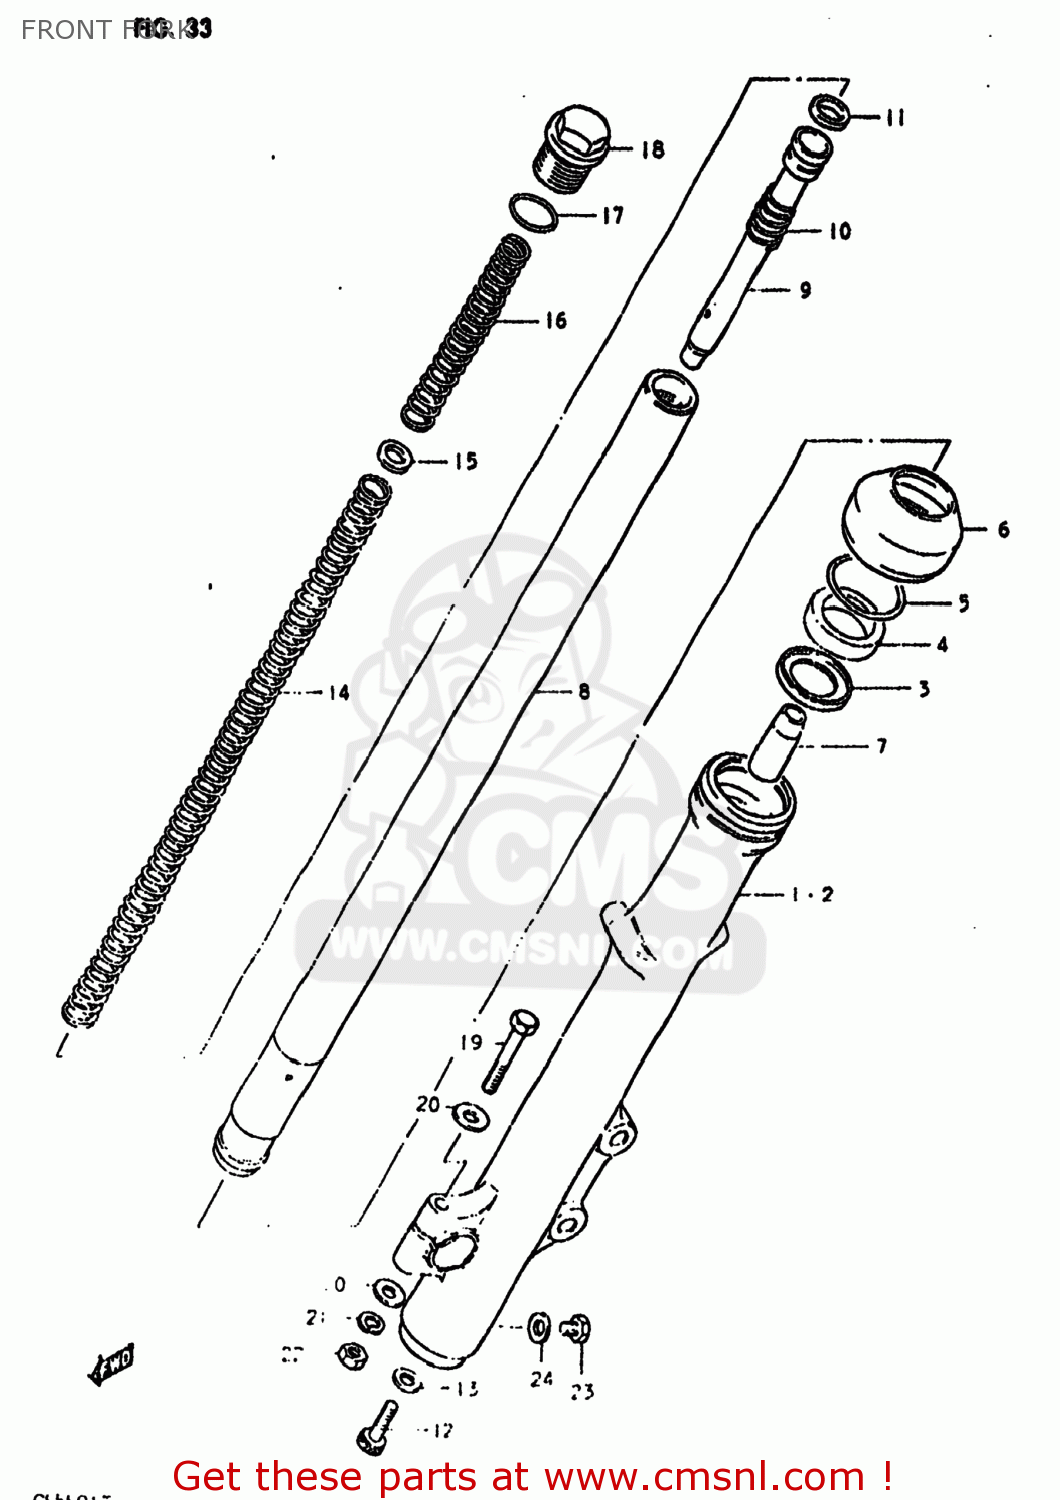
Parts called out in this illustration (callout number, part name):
0	DAMPER ASSEMBLY,LEFT
1	TUBE,OUTER,RIGHT
2	TUBE,FORK,LEFT,OUTER
3	SPACER,SEAL
4	OIL SEAL,FRONT FORK
5	CIRCLIP,FORK OIL SEAL
6	BOOT
7	PIECE,OIL LOCK
8	TUBE,FORK,INNER
9	CYLINDER,FRONT FORK
10	SPRING,FORK REBOUND
11	RING
12	BOLT(8X27)
13	GASKET (NAS)
14	SPRING,FRONT FORK MAIN,LOWER
15	WASHER,SPRING
16	SPRING,FRONT FORK,UPPER
17	O-RING
18	CAP,INNER TUBE
19	BOLT 8X50
20	WASHER
21	LOCK WASHER
22	NUT
23	BOLT
24	GASKET,DRAIN,PLUG (NAS)
